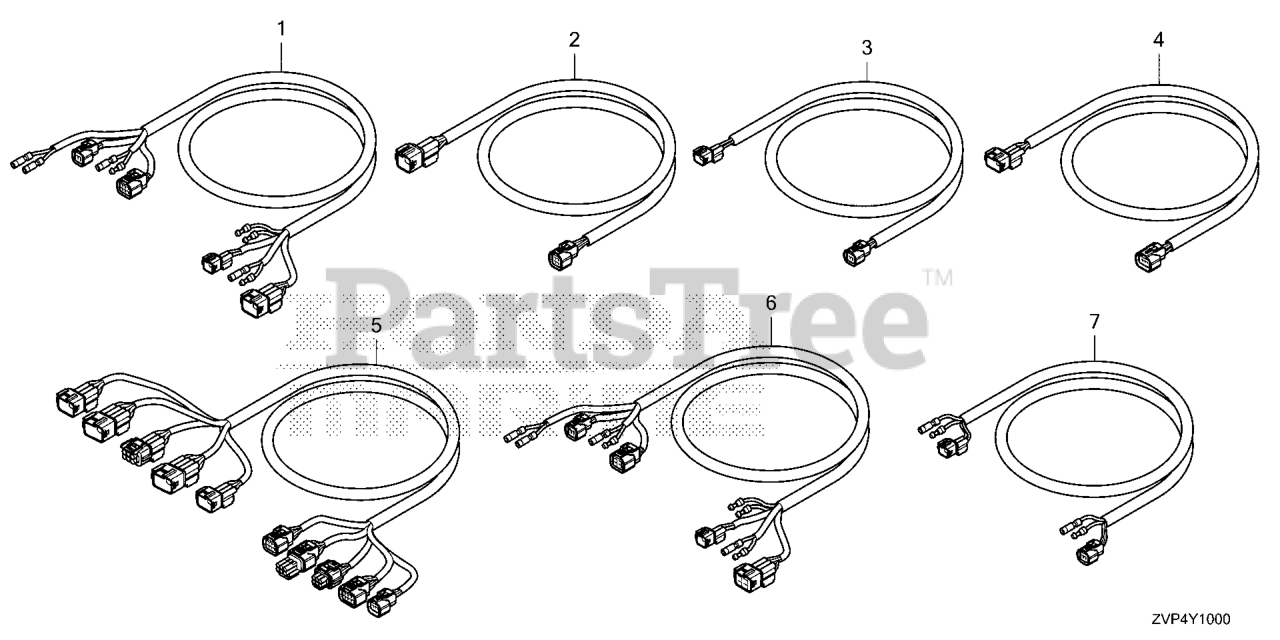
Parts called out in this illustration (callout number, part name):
1	HARNESS ASSY., EXTENSION (SWITCH PANEL)
2	HARNESS ASSY., EXTENSION (START STOP SWITCH)
3	HARNESS ASSY., EXTENSION (START STOP SWITCH ALL)
4	HARNESS ASSY., EXTENSION (POWER TRIM-TILT SWITCH)
5	HARN ASSY., EXTN
6	HARNESS ASSY., EXTENSION (SWITCH PANEL SMART)
7	HARNESS ASSY., EXTENSION (SWITCH PANEL)
